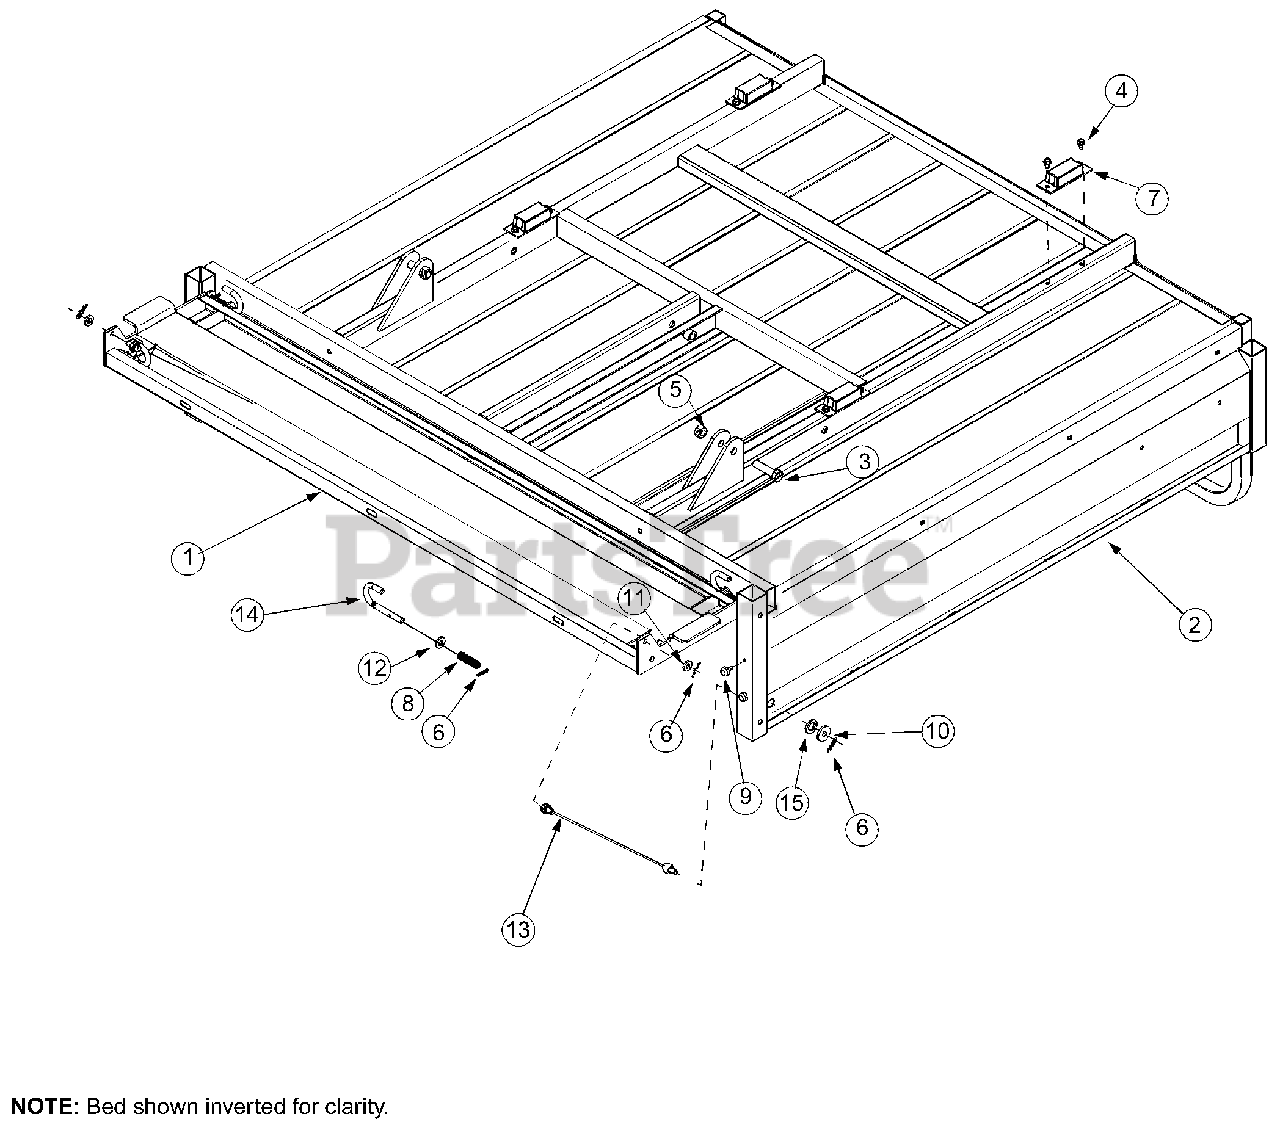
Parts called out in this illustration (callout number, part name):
1	Tailgate Assembly
2	Bed Assembly, Utility
3	Screw, Hex, 1/5-13 x 2.0, Gr5
4	Screw, Self-tapping, 1/4-20 x 0.500
5	Nut, Hex Lock, 1/2-13
6	Cotter Pin,.072 Dia x 1.13LG
7	Bumper, Extension Suspension
8	Compression Spring,.406 x.531 x 1.75 LG
9	Bumper,.62Dia x.3
10	Washer, Flat,.64 ID x 1.0 x.12
11	Washer, Flat,.344 x.750 x.120
12	Washer, Flat,.407 x.812 x.135 HDN
13	Cable, LIft 16.16 LG
14	Handle, Deck Release
15	Spacer, Shoulder.625 Dia x.324 Dia
